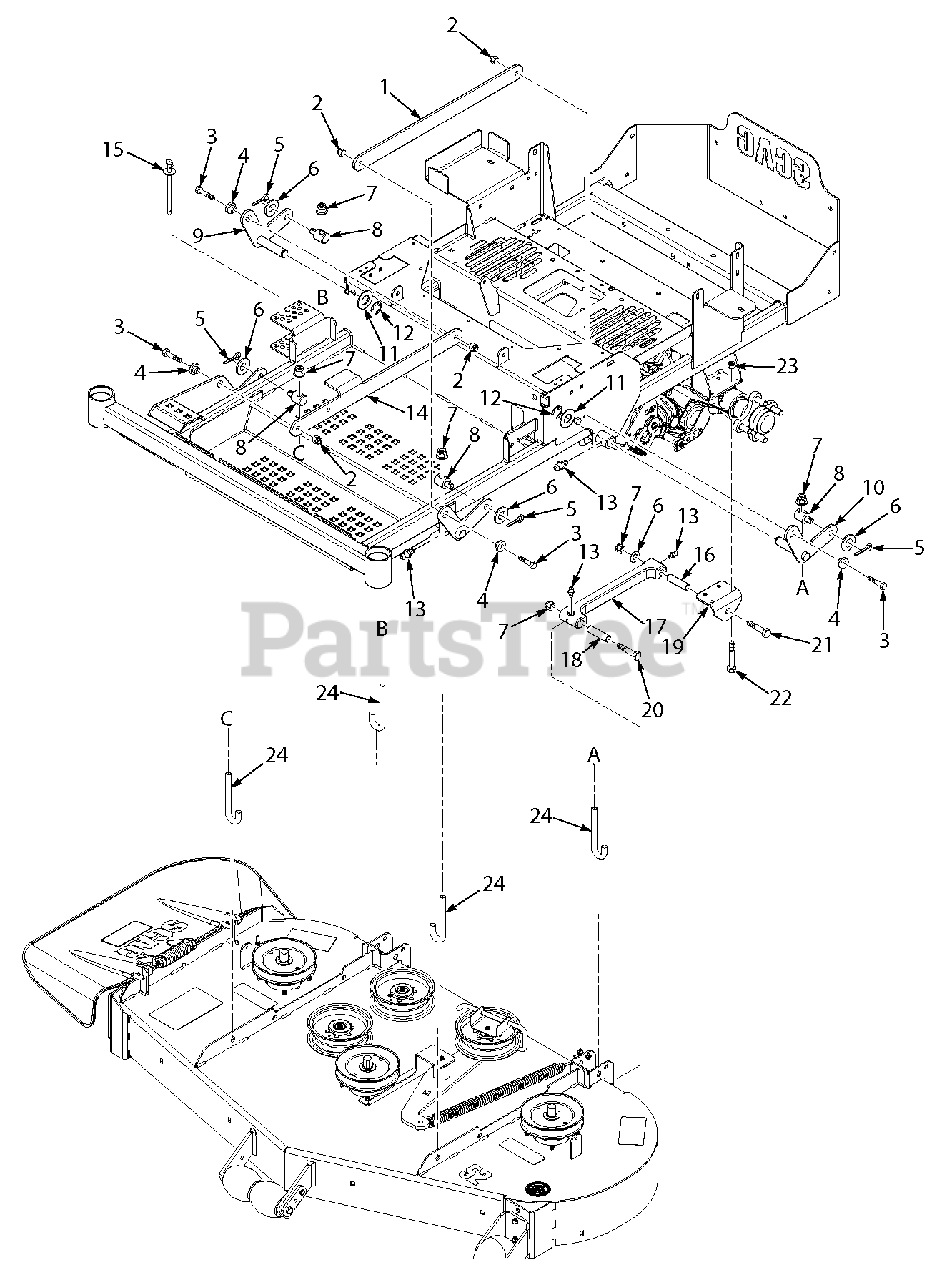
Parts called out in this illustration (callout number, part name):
1	Link, Deck Lift - LH
2	Nut, 3/8-16 Elastic Stop
3	Bolt, Hex Head 3/8-16 x 1-1/4"
4	Bushing
5	Cotter Pin, 3/16 x 1"
6	Flatwasher, 1/2-.531 x 1.062 x .095
7	Nut, 1/2-13 Elastic Stop
8	Joint, Swivel
9	Lift Bellcrank Weldment, RH
10	Lift Bellcrank Weldment, LH
11	Flatwasher, 3/4-.769 x 1.250 x .0598
12	Retaining Ring, .750 "E"
13	Grease Fitting, 1/4-28 Self Tap
14	Link, Deck Lift - RH
15	Pin Assembly, Deck Height
16	Spacer, Pusham - Axle
17	Pusharm Assembly, LH
17	Pusharm Assembly, RH
18	Spacer, Pusharm - Deck
19	Bracket, Pusharm
20	Bolt, Hex Head 1/2-13 x 3-1/2"
21	Bolt, Hex Head 1/2-13 x 2-1/2"
22	Bolt, Hex Head 5/16-18 x 3"
23	Nut, 5/16-18 Elastic Stop
24	Rod, Deck Lift
